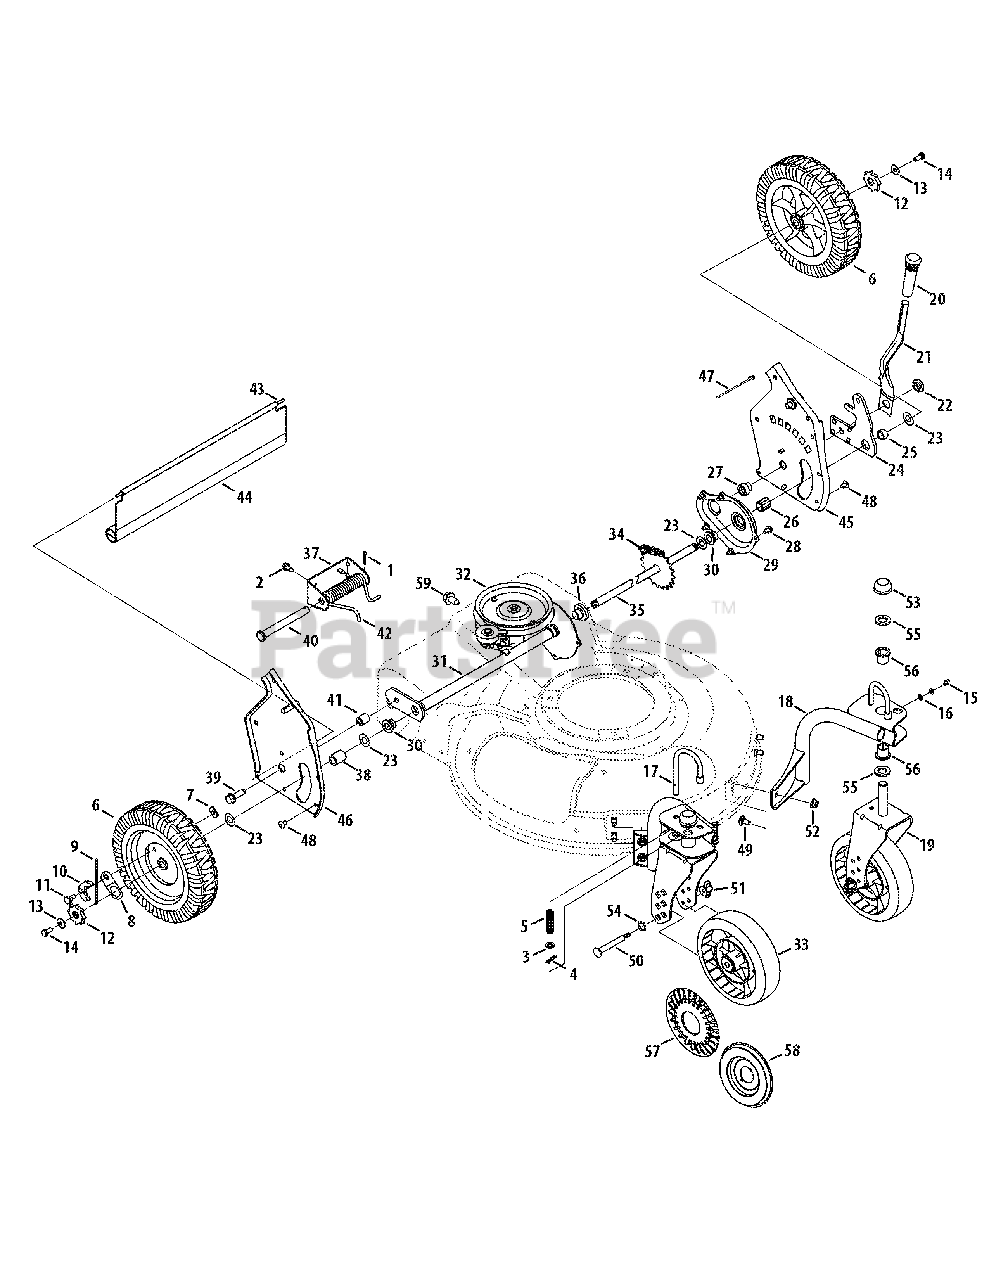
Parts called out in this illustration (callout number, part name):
1	Cotter Pin
2	Screw 1/4-14 x .825
3	Flat Washer.330 ID x.630 OD
4	Cotter Pin
5	Compression Spring
6	Wheel, 9 x 2.125
7	Top Lock Tab Weld Nut 1/4-20
8	Ratchet Pawl Plate
9	Plastic Spring Ratchet
10	Pawl RH
10	Pawl LH
11	Shlder Screw.340 ID x.285 OD
12	Wheel Ratchet
13	Bell Washer.265 ID x.75 OD
14	Hex Cap Screw 1/4-20 x.620
15	Grease Fitting
16	Flat Washer.203 ID x.403 OD
17	Wheel Pin Lock
18	Caster Assembly RH
18	Caster Assembly LH
19	Caster Bracket Assembly RH
19	Caster Bracket Assembly LH
21	Spring Lever
22	Shoulder Nut.825 x .165 Lg.
23	Flat Washer .508 ID x 1.0 OD
24	Pivot Arm Assembly
25	Spacer .510 ID x .70 OD
26	Slv Bearing .504 ID x .830 OD
27	Shlder Spacer, .385ID x .715Lg
28	Tap Screw 1/4-20 x .375
29	Chain Cover Assembly
30	Flge Bearing .506 ID x .590 Lg
31	Transmission Axle Assembly
32	Transmission Ass’y Complete
33	Wheel 7 x 2
34	Chain
35	Rear Axle Assembly
36	Flge Bearing .506 ID x .715 Lg
37	Height Adjustment Spring Brkt.
38	Spacer .550 ID x .750 OD
39	Screw 3/8-16 x .25
40	Clevis Pin .50 Dia x 4.82 Lg.
41	Spacer .385 ID x .624 OD
42	Torsion Spring
43	Trail Shield Wire
44	Trail Shield
45	Handle Bracket Assembly - LH
46	Handle Bracket Assembly - RH
47	Cable Tie
48	Screw 1/4-14 x.500
49	Carriage Bolt 5/16-18 x.62
50	Caster Axle
51	Wing Nut
52	Flange Lock Nut 5/16-18
53	Push Cap
54	Wave Washer.531 ID x.781 OD
55	Flat Washer.640 ID x 1.12 OD
56	Flange Bearing
57	Hubcap - Spoke w/ Hole
58	Hubcap - Radial Spoke
59	Screw, 5/16-18 x .625
